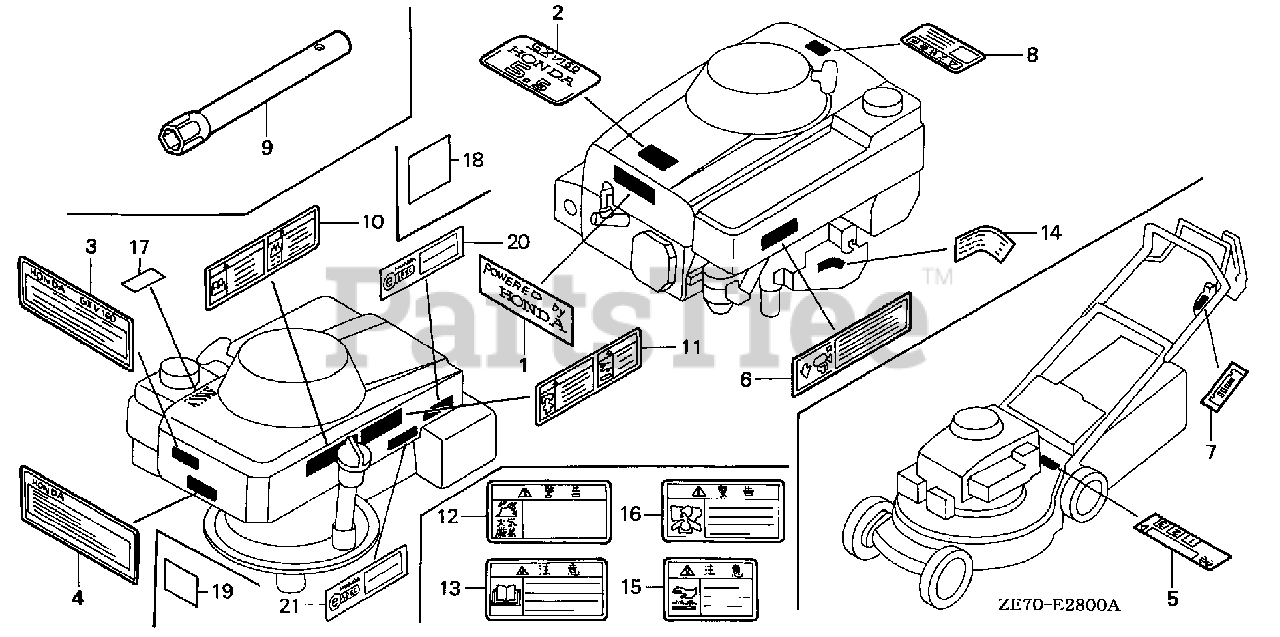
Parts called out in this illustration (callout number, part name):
2	MARK, EMBLEM (5.5 ES)
2	MARK, EMBLEM (5.5) (AH)
6	MARK, HONDA
9	WRENCH, BOX (P21)
19	MARK, TYPE (N52)
